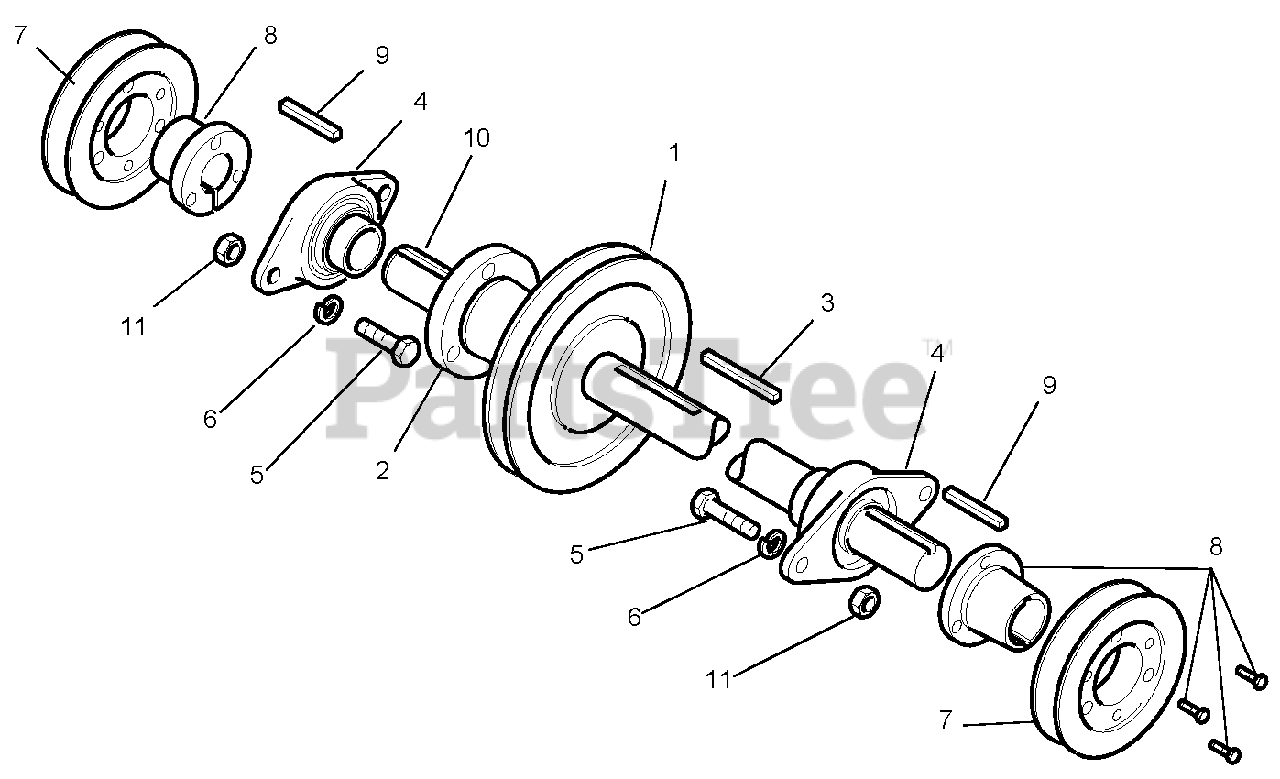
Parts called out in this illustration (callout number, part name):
1	Pulley, 1-Belt 6.6 PD
2	Bushing, Split Tapered
3	Key, Pulley
4	Bearing Flange, 2-Bolt
5	Cap Screw, Hex Head .437-14 x 1.25
6	Washer, Lock .437
7	Pulley, 1-Belt 4.4 PD
8	Bushing, Split Tapered
9	Key, Square .25 x .25 x 1
10	Jackshaft, Front
11	Nut, Hex .437
